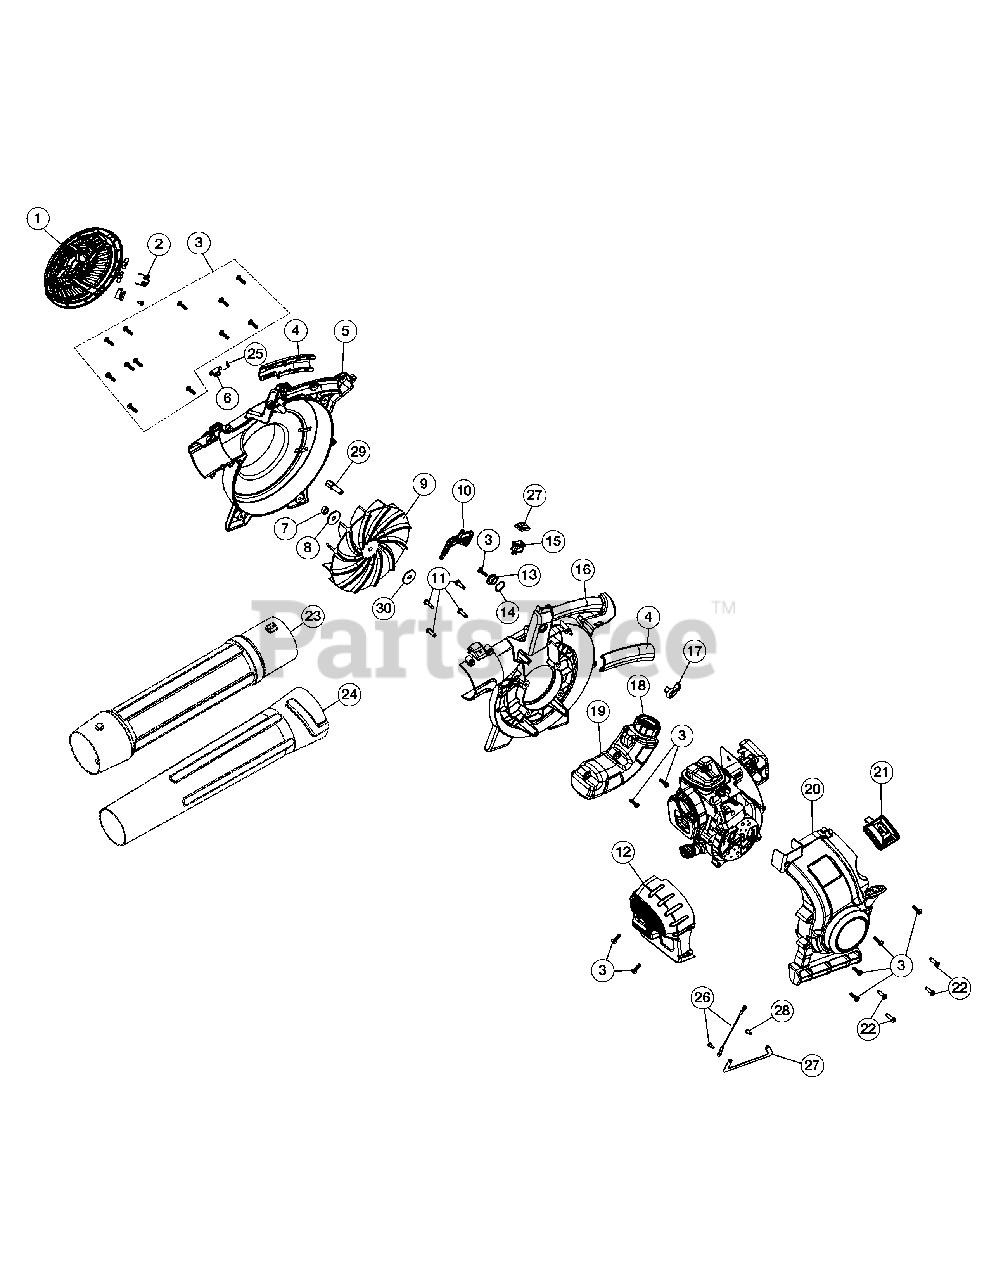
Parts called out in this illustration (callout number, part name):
1	Intake Cover Assembly
4	Handle Grips
5	Impeller Housing
6	Latch Tube
10	Throttle Trigger
11	Screw
12	Muffler Cover
13	Inner Trigger Lock
14	Wavey Washer
16	Impeller Housing
17	Outer Trigger Lock
19	Fuel Tank Assembly
20	Engine Cover Assembly
21	Spark Plug Cover
23	Upper Tube
24	Lower Tube
25	Latch Spring
26	Wire Ground
27	Strap Ground
28	Screw
